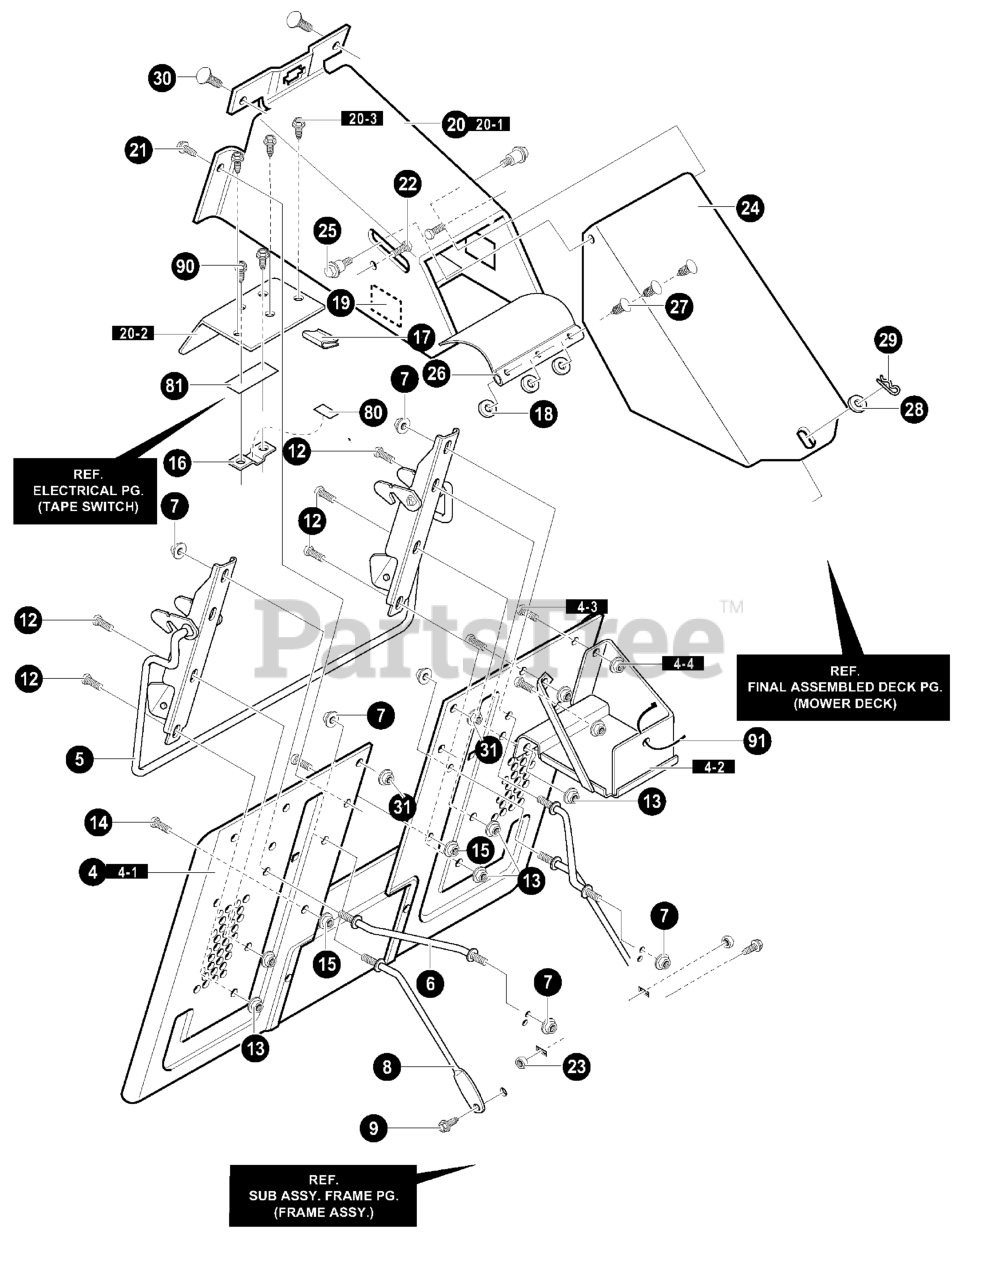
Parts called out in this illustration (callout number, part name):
4	ASSY, BACK PLATE/BATTERY
4-1	ASM. BACKPLATE FLAT
4-2	BATTERY TRAY ASM.
4-3	SCREW, 5/16-18 x 0.50 HHC
4-4	NUT, 5/16-18 HEXWDFLLK WHIZ
5	WELDMENT - LATCH LEVER
6	ROD, BRACE
7	NUT, 3/8-16 HWDFL WHIZ-LOCK
8	ROD, BRACE
9	SCREW, 5/16-18 x 0.75 HHWATAP
12	SCREW 5/16-18X.75 HXWDFL
13	NUT, 5/16-18 HEXWDFLLK WHIZ
14	SCREW 5/16-18X.75 HHWATAP
15	NUT, 5/16-18 HEXWDFLLK WHIZ
16	BRACKET, FLEX SWITCH MOUNTING
17	WIRE CLIP, ADHESIVE
18	FLATWASHER, .250X.56X.047
19	PAD, ADHESIVE 1.00X1.50X.12
20	ASM., T/A SHIELD & UPPER CHUTE
20-1	CHUTE WELD ASM. UPPER
20-2	SHIELD, TRANSAXLE
20-3	SCREW, 1/4-20X.63 HHWATAP
21	SCREW, 5/16-18 x.75 HHC
22	BOLT, 5/16-18X.75 CARR
23	NUT, 5/16-18 HEXWDFLLK WHIZ
24	MIDDLE CHUTE ASSY
25	BOLT, SHOULDER, (9X57)
26	FLAP, CHUTE
27	FASTENER, RATCHET
28	FLATWASHER
29	PIN, HAIR .38DIAX1.64LG
30	BOLT, 5/16-18X.75 CARR.
31	NUT, 5/16-18 HEXWDFLLK WHIZ
80	TAPE, DOUBLE SIDED FOAM 3/4" WD
81	TAPE, DOUBLE SIDED FOAM 3/4" WD
90	SCREW, 1/4-20X.63 HHWATAP
91	CABLE TIE
